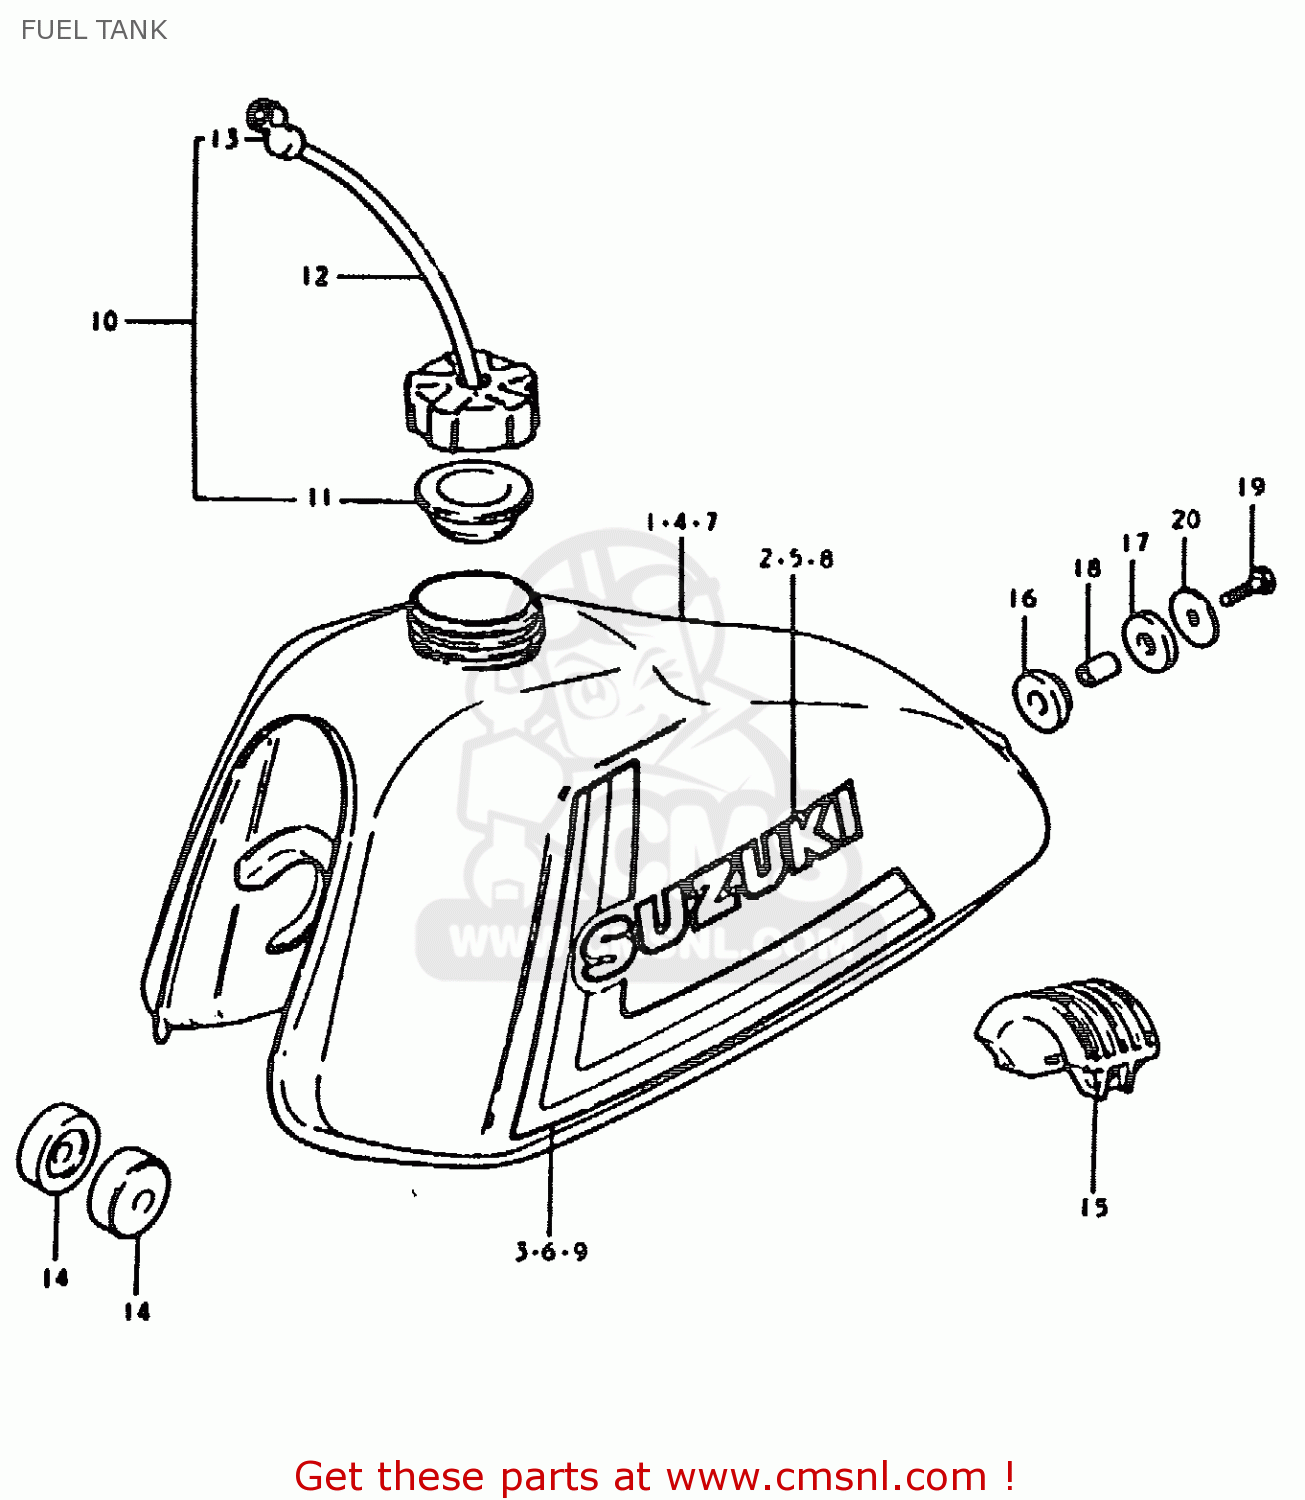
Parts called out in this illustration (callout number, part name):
1	TANK, FUEL (RED)
2	EMBLEM
3	TAPE SET
4	TANK, FUEL (BLUE)
5	EMBLEM
6	TAPE SET
7	TANK, FUEL
8	EMBLEM
9	TAPE SET
10	CAP SET,FUEL TANK
11	GASKET,FUEL TANK CAP (NAS)
12	HOSE
13	CLAMP,FUEL TANK BREATHER HOSE
14	CUSHION
15	CUSHION,FUEL TANK
16	CUSHION
17	CUSHION
18	SPACER(8.5X12X19)
19	BOLT (8X30)
20	WASHER (8.5X29X1.6)
